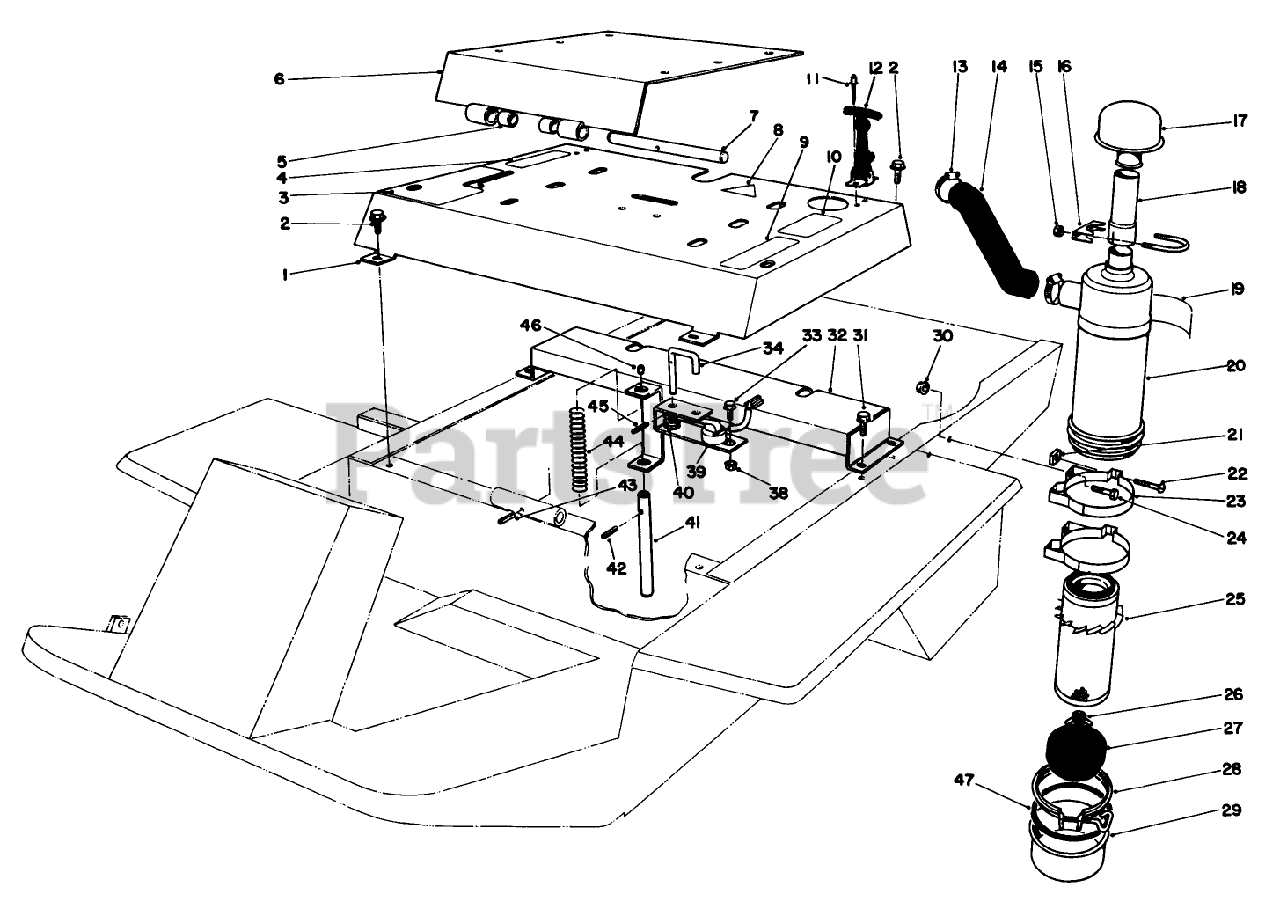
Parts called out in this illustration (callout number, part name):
1	Cover-Seat Support (Incl. Ref. #4, 5, 9 & 10)
2	SCREW-HHFTF
3	DECAL - LIFT CONTROL
4	DECAL-WARNING
5	.503ID X .875LG BSHG
6	Mounting-Seat (Incl. Ref. #5)
7	SHAFT-PIVOT, SEAT
8	DECAL-DANGER
9	DECAL - CAUTION
10	DECAL-REFUELING
11	RIVET
12	Assembly-Handle
13	CLAMP-HOSE
15	NUT-HEX
16	CLAMP-MUFFLER
18	Tube-Air Cleaner
19	DECAL-INSTALLATION
20	Assembly-Air Cleaner (Incl. Ref. #18 & 24-28)
21	NUT-SQUARE
22	SCREW
23	Assembly-Mounting, Band (Incl. Ref. #20 & 21)
24	SCREW-HH
25	ELEMENT ASM
26	NUT AND GASKET ASM
27	SKIRT-BAFFLE
28	CLAMP ASM
29	A/C CUP ASM
30	NUT-HF
31	SCREW-HHF
32	Seat Support
33	SCREW-HHF
34	SEAT SWITCH PIN
35	WASHER-LOCK
38	NUT-HF
39	SWITCH ARM
40	SPRING
41	PIN-SWITCH, SEAT
42	PIN-ROLL, SLOTTED
43	PIN-ROLL, SLOTTED
44	SPRING-COMP
45	PIN-ROLL, SLOT
46	PIN-PEDAL
47	GASKET
